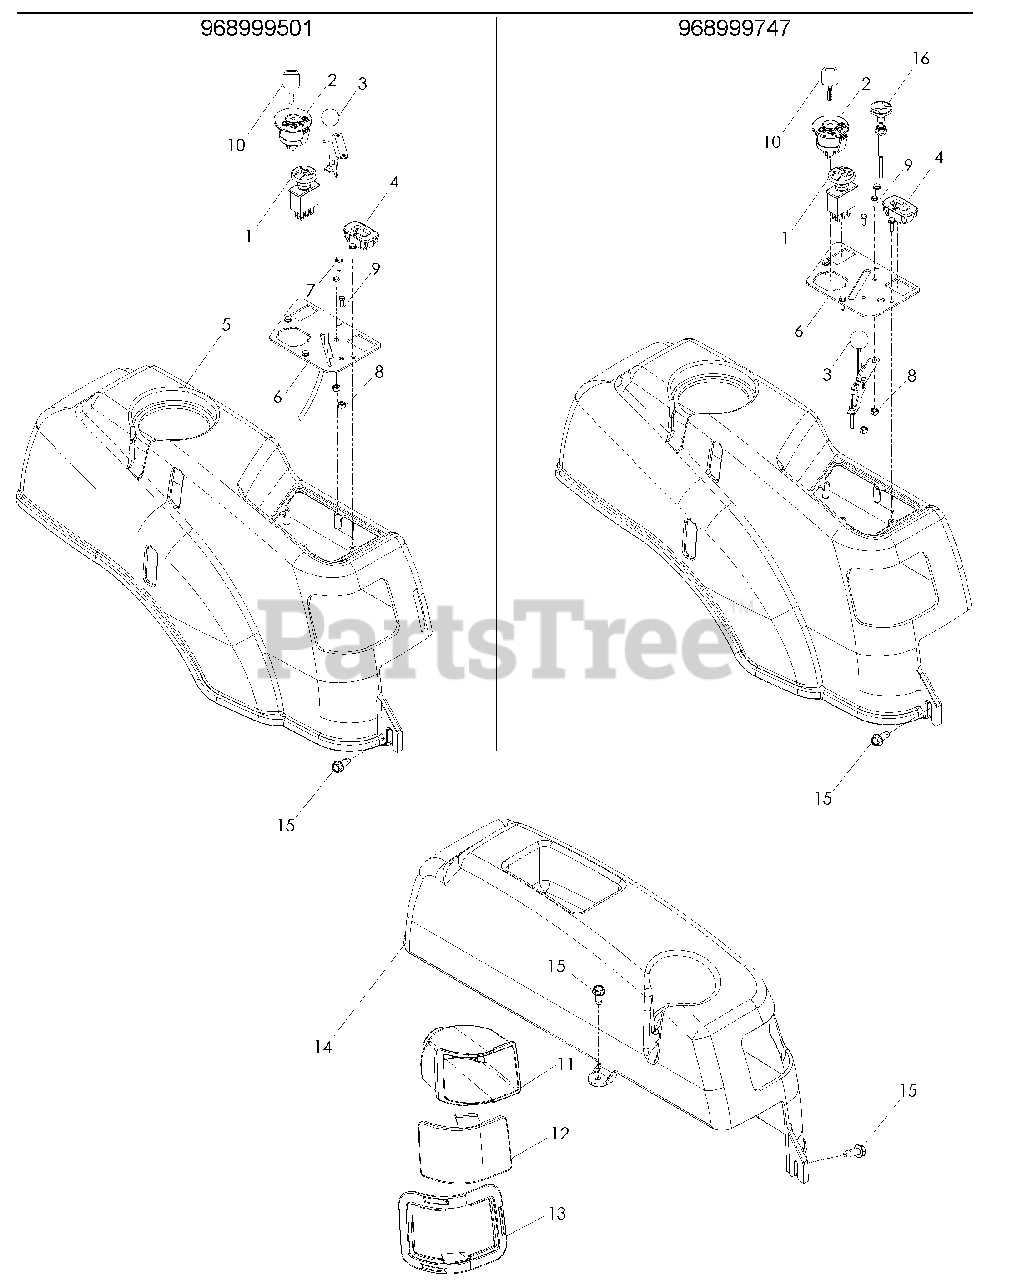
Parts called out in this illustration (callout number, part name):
1	BLADE SWITCH
2	IGNITION SWITCH
3	THROTTLE CABLE
4	HOUR METER
5	FENDER, CONSOLE
6	CONSOLE PLATE
7	SCRW, #10-12 x 3/4, WASH HD
8	NUT, #10-24, NYLOC
9	SCREW, #10-24 x 1/2
10	KEY
11	HEADLIGHT REFLECTOR, LT
12	LENS, COLORED, LT
13	RIM, HEADLIGHT, RT
14	FENDER, LT
15	SCREW, 1/4-20 x 5/8, SLF TAP
16	CHOKE CONTROL
